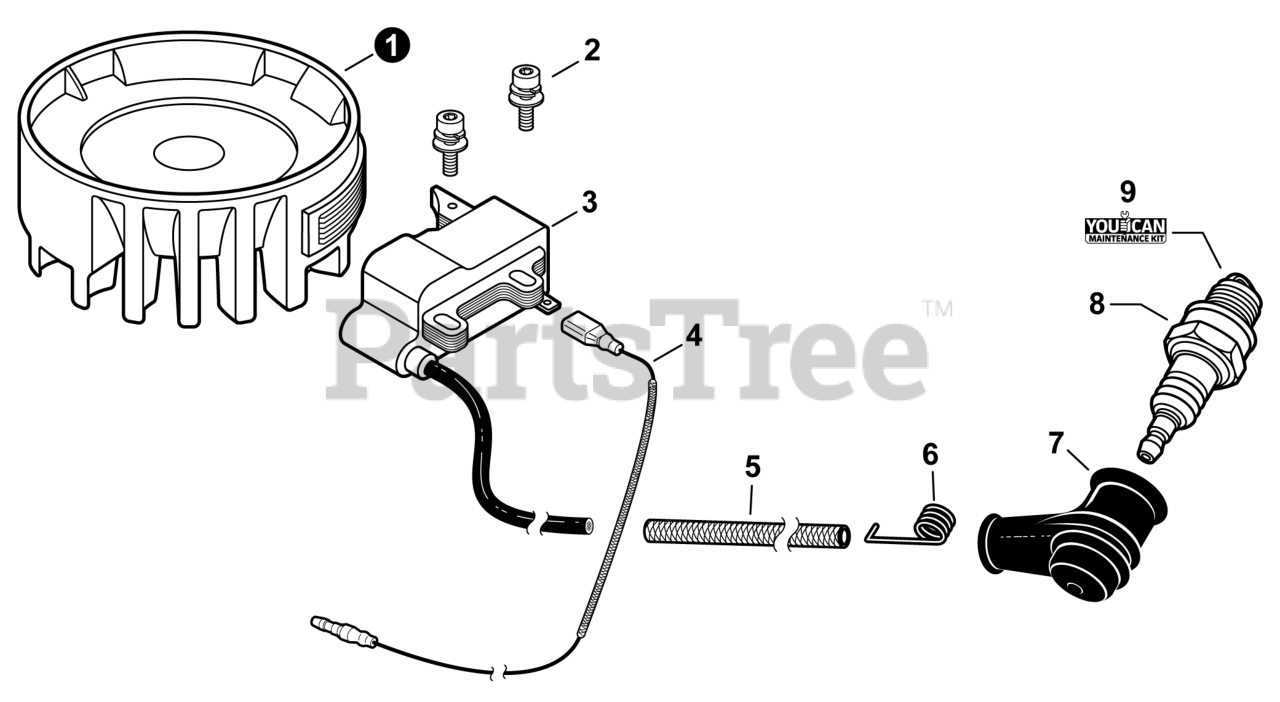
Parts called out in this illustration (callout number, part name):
1	FLYWHEEL
2	BOLT 4x20
3	COIL, IGNITION
4	LEAD - IGNITION
5	TUBE, INSULATOR 7x8.6x55
6	TERMINAL, SPARK PLUG
7	CAP, SPARK PLUG
8	SPARK PLUG - BPMR8Y
9	TUNE-UP KIT - YOUCANT
